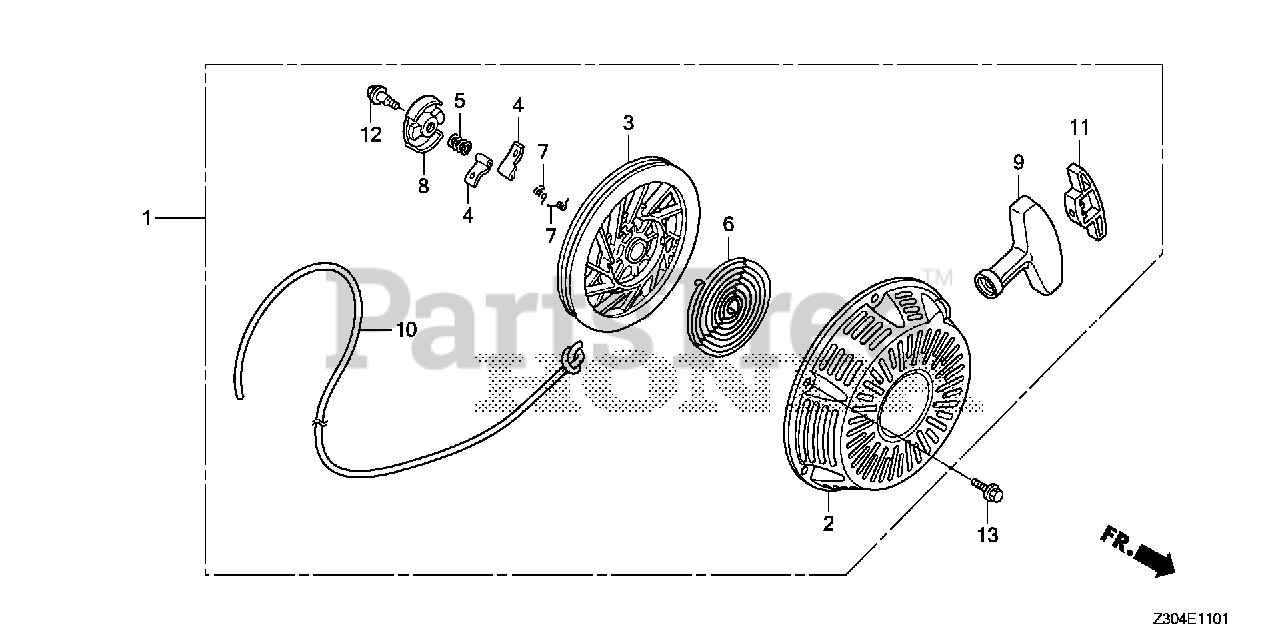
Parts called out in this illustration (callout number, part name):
1	STARTER ASSY., RECOIL *NH1* (COO) (BLACK)
2	CASE, RECOIL STARTER *NH1* (BLACK)
3	PULLEY, RECOIL STARTER
4	RATCHET, STARTER
5	SPRING, FRICTION
6	SPRING, STARTER RETURN
7	SPRING, RATCHET
8	RETAINER, SPRING
9	GRIP, STARTER
10	ROPE, RECOIL STARTER
11	GRIP, REINFORCEMENT
12	SCREW, CENTER
13	BOLT, FLANGE (6X10)
